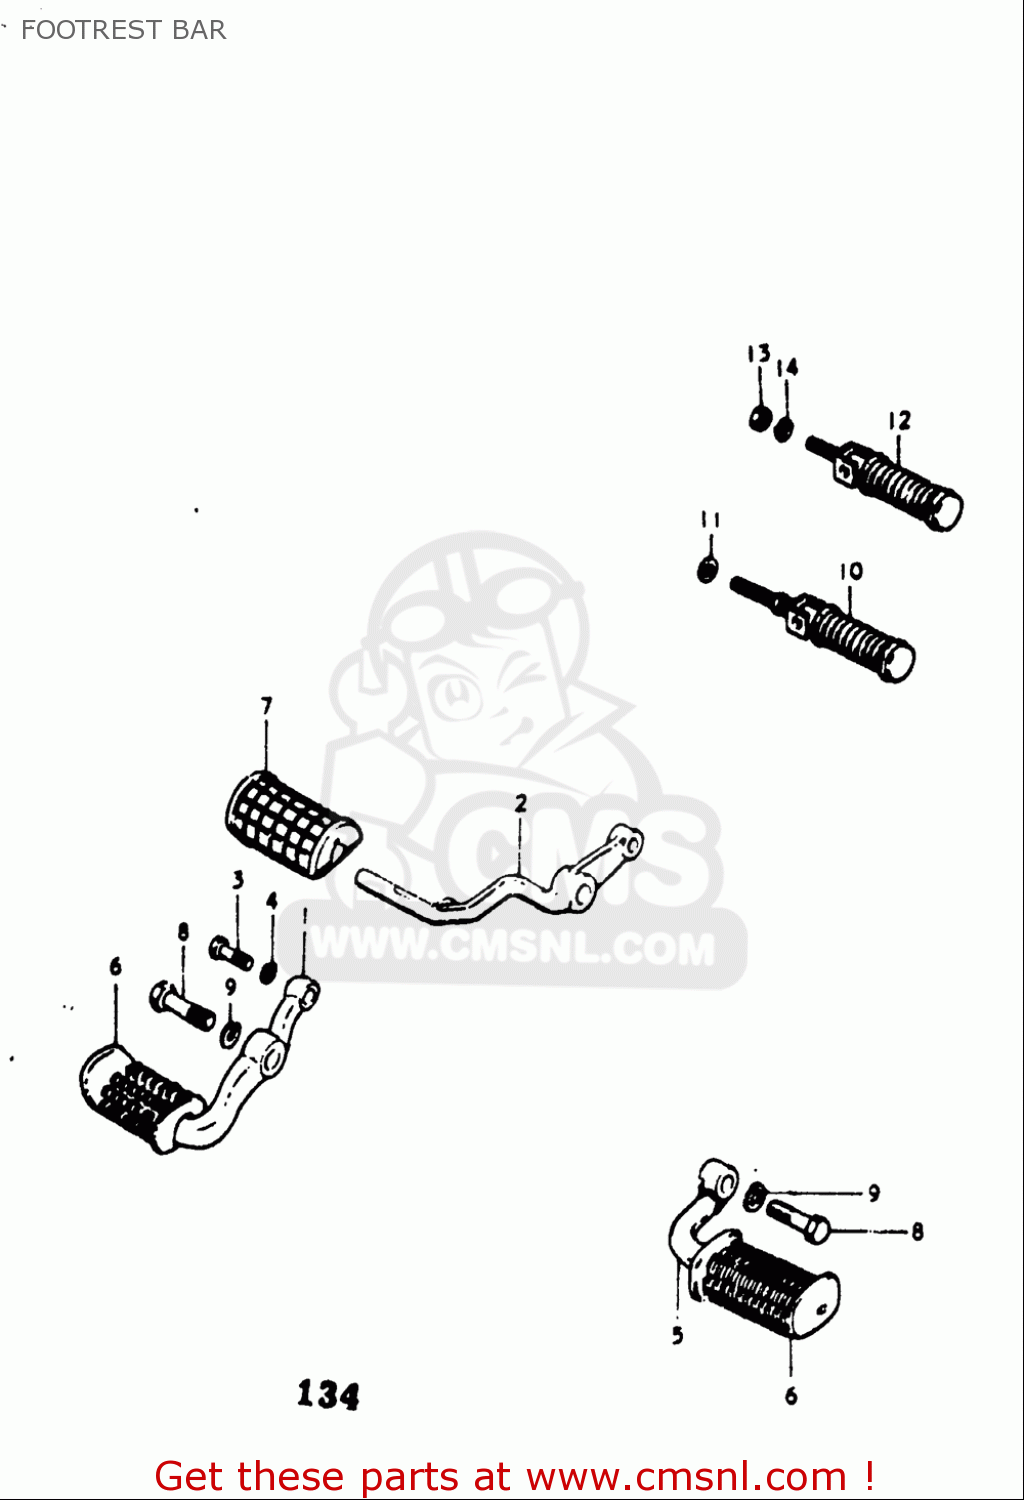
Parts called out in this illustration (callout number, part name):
2	BAR,FRONT FOOTREST,RIGHT
3	BOLT
4	WASHER,LOCK
5	BAR,FOOTREST,LEFT
7	RUBBER,FR FOOTREST
8	BOLT
9	WASHER,LOCK
10	FOOTREST ASSY,PILLION
11	WASHER
13	NUT
14	WASHER,LOCK
